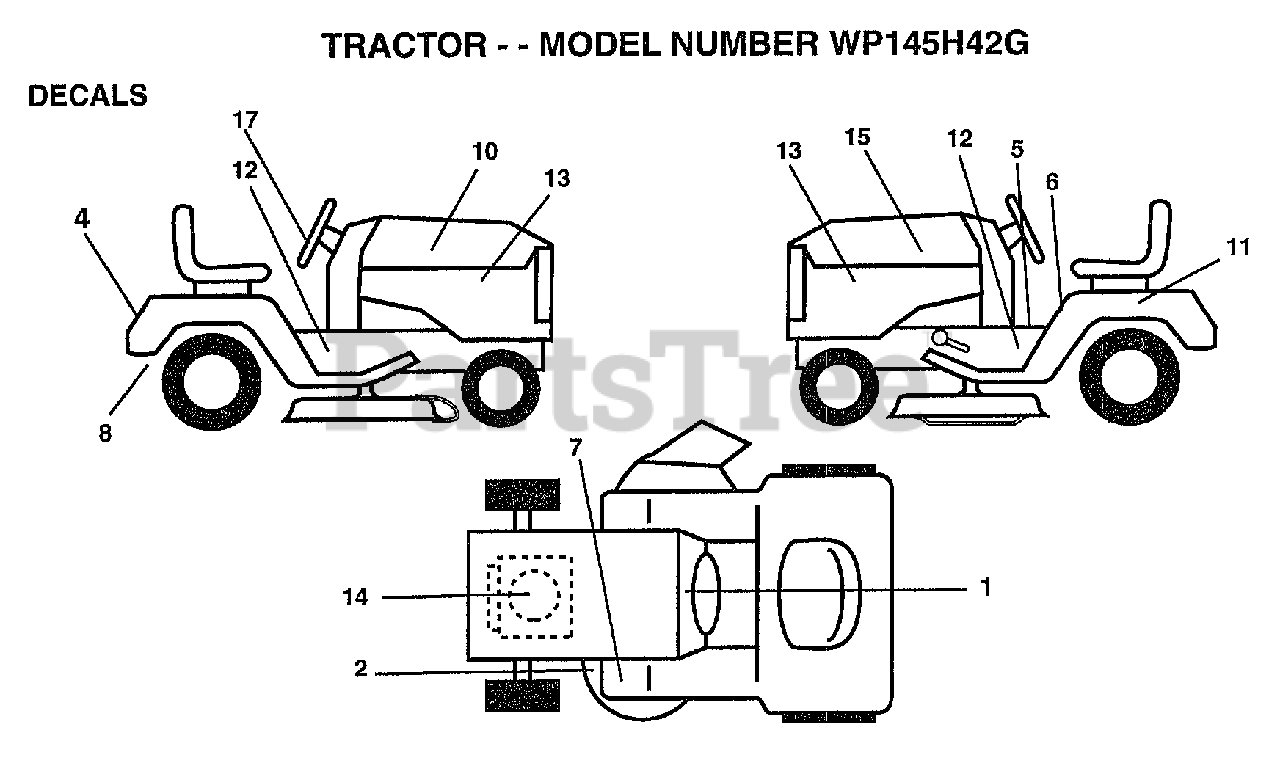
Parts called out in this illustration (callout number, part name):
1	"DECAL-INST,OPER"
2	"DECAL-SCHEM,BELT"
4	DECAL, FENDER LOGO
5	DECAL BRAK PARK
6	"DECAL DANGER,FEND"
8	DECAL DRAWBAR LH
10	DECAL.HOOD.RH
11	DECAL.BATRY.3-3908
12	DECAL CHAS 42 HYD
13	DECAL.WP145H42A
14	DECAL.ENGINE
15	DECAL.HOOD.LH
17	DECAL, INSERT
